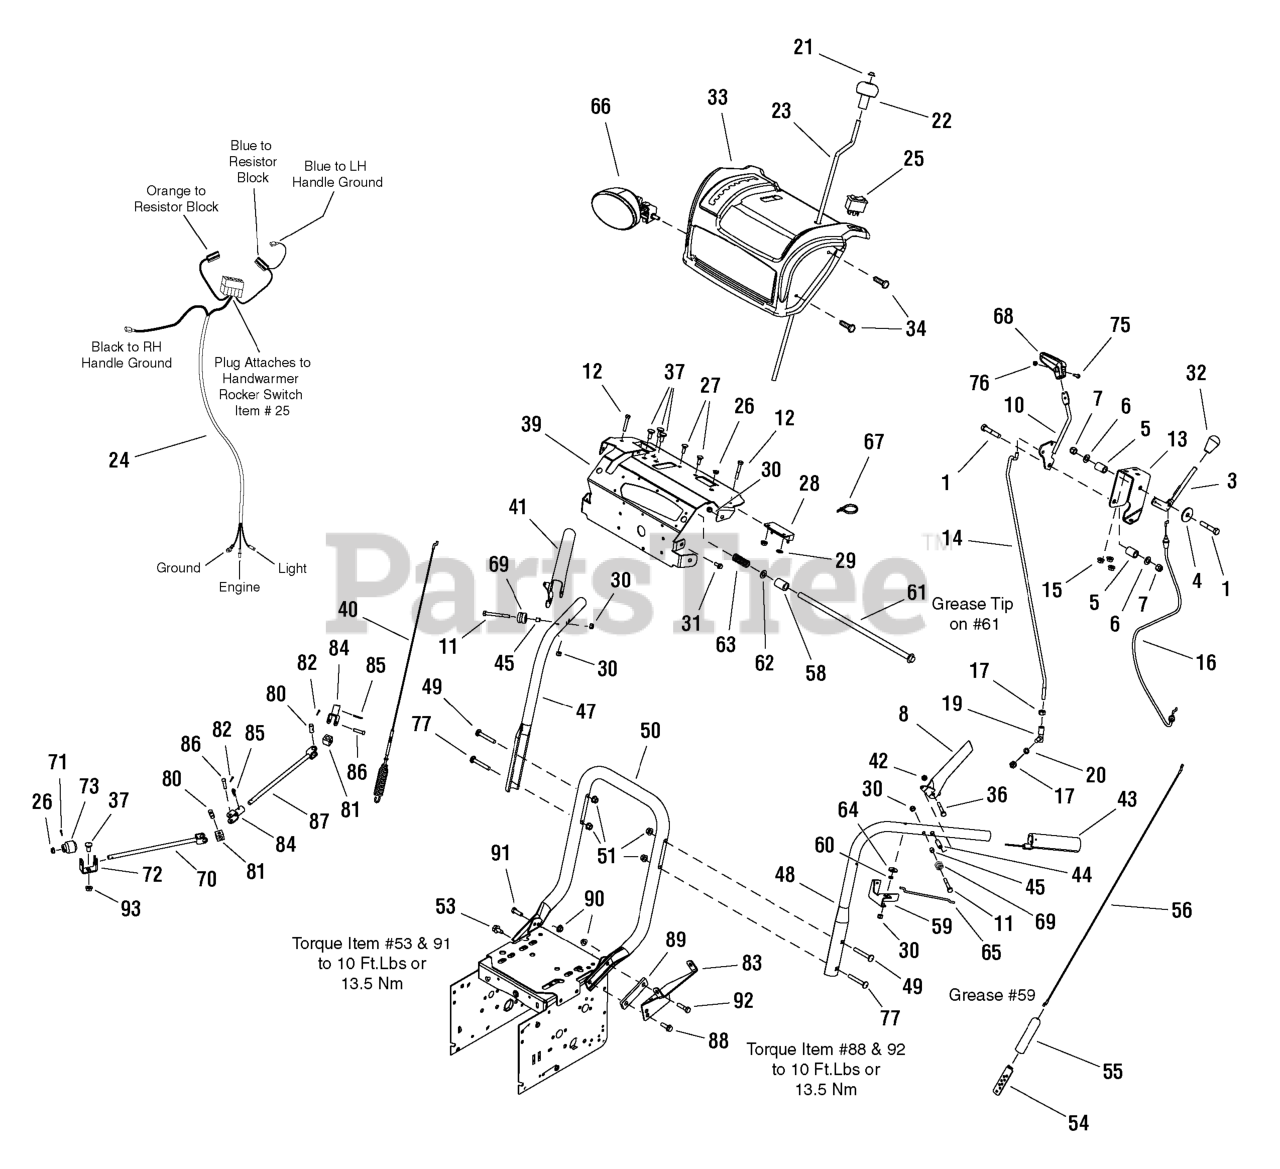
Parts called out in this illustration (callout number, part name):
1	CAPSCREW, Hex Head 3/8-16 x 2 G5
3	ROD, Remote Chute
4	WASHER, 3/8
5	SPRING, Compression .509 DIA x 3/4
6	WASHER, 3/8
7	NUT, Hex Lock ESNA Light 3/8-16 NC3B
8	HANDLE, Clutch L.H.
10	ROD & PLATE ASSEMBLY, Speed Control
11	CAPSCREW, Hex Head 1/4-20 x 2-1/2 G5
12	CAPSCREW, Hex Head 1/4-20 x 1-3/4 G5
13	BRACKET, Speed & Deflector Control 12GA
14	ROD, Link Speed Control
15	NUT, Hex Flange 5/16-18, Whiz Lock Small
16	CABLE, Deflector Control
17	NUT, Hex 5/16-24
19	BALLJOINT, Steel
20	LOCKWASHER, Spring 5/16
21	NUT, Push Pal 5/16 Diameter Stud Capped
22	KNOB, Spinner
23	ROD, Chute Control
24	HARNESS, Wiring Handwarmers
25	SWITCH, Rocker Hand Warmer
27	CARRIAGE BOLT, 1/4-20 x 3/4 G5
28	RESISTOR BLOCK, Hand Warmers
29	NUT, Hex KEPS 1/4-20 Conical Washer
30	NUT, Hex Lock ESNA Light 1/4-20
31	SCREW, Hex Washer Head Taptite 1/4-20 x 5/8
32	KNOB, Interior Thread 3/8-16
33	COVER, Panel 16GA
34	SCREW, Truss Head Torx Drive 1/4-20 x 3/4
36	CAPSCREW, Hex Head 1/4-20 x 1-1/2 G5
37	CARRIAGE BOLT, 5/16-18 x 3/4
39	SUPPORT, Dash Panel Cover
40	CABLE & SPRING ASSEMBLY, Auger Drive R.H.
41	HANDLE, Clutch R.H.
42	NUT, Hex Centerlock 1/4-20
43	GRIP, Black Soft 1" Diameter
43	HAND GRIP, Heated 1" Diameter
44	SPACER, Handle
45	SPACER
47	HANDLE, Upper R.H. Tubular
48	HANDLE, Upper L.H. Tubular
49	CARRIAGE BOLT, 5/16-18 x 2-1/4 G5
50	HANDLE, Lower Tubular
51	NUT, Hex Flange 5/16-18 ESNA
53	SCREW, Hex Washer Head Taptite 5/16-18 x 3/4
54	BRACKET, Cable Adjusting 13GA
55	BOOT, Spring End Cover
56	CABLE, Drive
58	SPACER, 1/2 x 7/8 x 1 3/16
59	BRACKET, Free Hand Control
60	SPACER, Powdered Metal
61	ROD & SPRING ASSEMBLY, w/Pin
62	WASHER, 1/2
63	SPRING, Compression
64	WASHER, 1/4
65	ROD, Hold Down
66	HEADLIGHT ASSEMBLY, Oval Clear
67	TIE, Self Locking
68	KNOB, Slot Speed
69	SPOOL CABLE, Auger Control
70	ROD & YOKE ASSEMBLY, Chute
71	PIN, Spring
72	SUPPORT, Worm 10GA
73	WORM, Chute L.H.
75	SCREW, Round Head Phillips #10-24 x 3/4
76	NUT, Hex Lock 10-24 W/Nylon Insert
77	CARRIAGE BOLT, 5/16-18 x 3/4
80	PIN, Universal Joint
81	BLOCK, Universal Pivot
82	PIN, Cotter
83	SUPPORT, Chute Rod
84	YOKE & TUBE ASSEMBLY, Chute
85	PIN, Hair Chute Gear
86	PIN, Clevis
87	ROD & YOKE ASSEMBLY, Chute
88	SCREW, Hex Washer Head Taptite 5/16-18 x 1
89	SPACER, Block
90	NUT, Hex Flange 5/16-18 Two-Way Lock
91	CAPSCREW, Hex Head, 5/16-18 x 1
92	CAPSCREW, Hex Head, 5/16-18 x 1 1/4
93	NUT, Hex KEPS 5/16-18 Conical Washer
